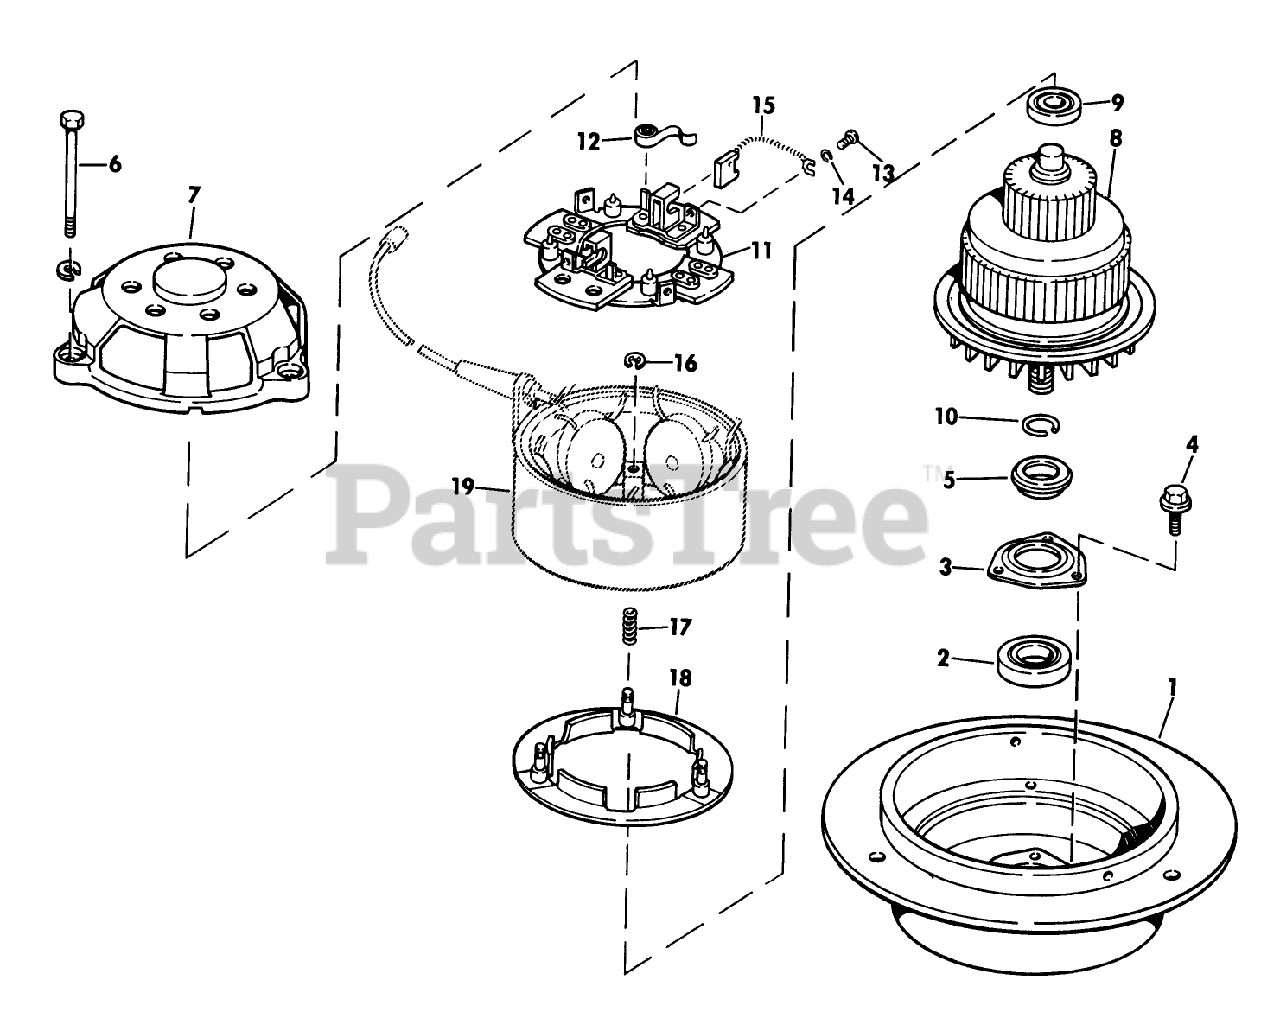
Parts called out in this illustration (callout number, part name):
1	End Bell-Motor
6	Screw-Motor Assembly
15	Brush
18	Brake Disc
19	Stator Assembly
